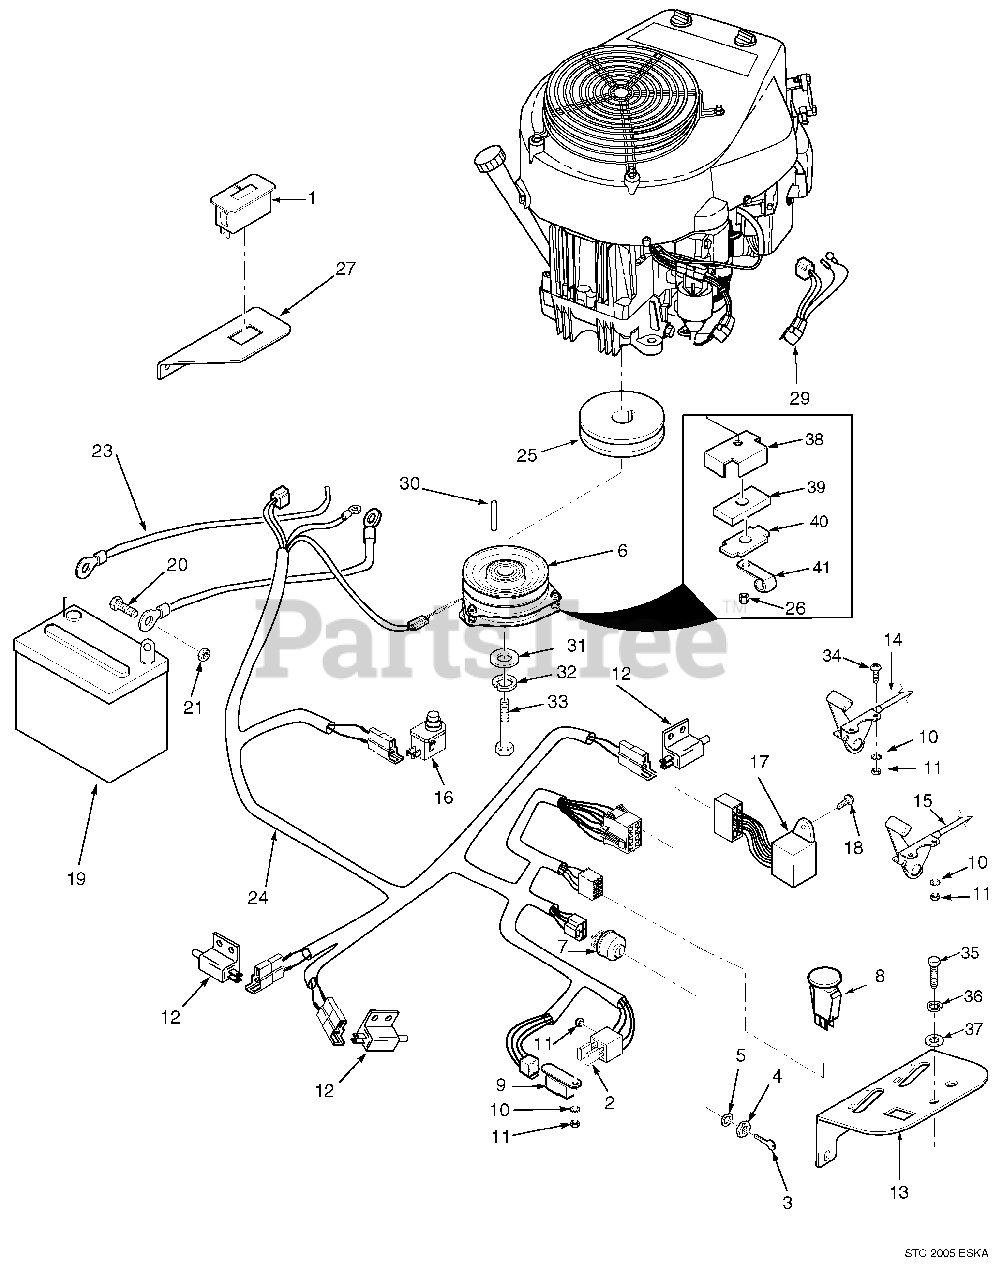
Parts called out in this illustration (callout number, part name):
1	Hourmeter
2	Fuse, 20 amp
3	Key, Ignition
4	Nut, Hex 5/8-32
5	Lockwasher, 5/8" Internal
6	Electric PTO Clutch GT3.5
7	Switch, Ignition
8	Switch, PTO
9	Relay
10	Lock Washer, #10 External Tooth
11	Nut, Hex #10-32
12	Switch, N/O
13	Panel, Instrument
14	Choke & Throttle Control
14	Choke Control
15	Throttle Control
16	Switch, Seat
17	Module, Interlock
18	Screw, #10-32 x .5" Phillips Head
19	Battery, 300CCA
20	Bolt, Hex Head 1/4-20 x .5"
21	Nut, Hex 1/4-20
22	Cable, Battery Black
23	Cable, Battery Red
24	Wiring Harness, Main
25	Pulley, 5.45 OD x 1.125 Bore
26	Nut, Elastic Stop 5/16-18 Key
27	Mounting Bracket, Hour Meter
28	Screw, #10-32 x 1.5" Phillips Head
29	Adaptor, Wiring Harness
30	Key, 1/4 x 1/4 x 3-1/4"
31	Flatwasher, 7/16-.469 x 1-3/4" x 1/4"
32	Lockwasher, 7/16"
33	Bolt, Hex Head 7/16-20 x 2-1/2" UNF
34	Screw, #10-32 x 3/4"
35	Bolt, Hex Head 5/16-18 x 3/4"
36	Lockwasher, 5/16
37	Flatwasher, 5/16-.375 x .875 x .083
38	Backing Plate
39	Rubber Pad, Clutch Stop
40	Plate, Backing
